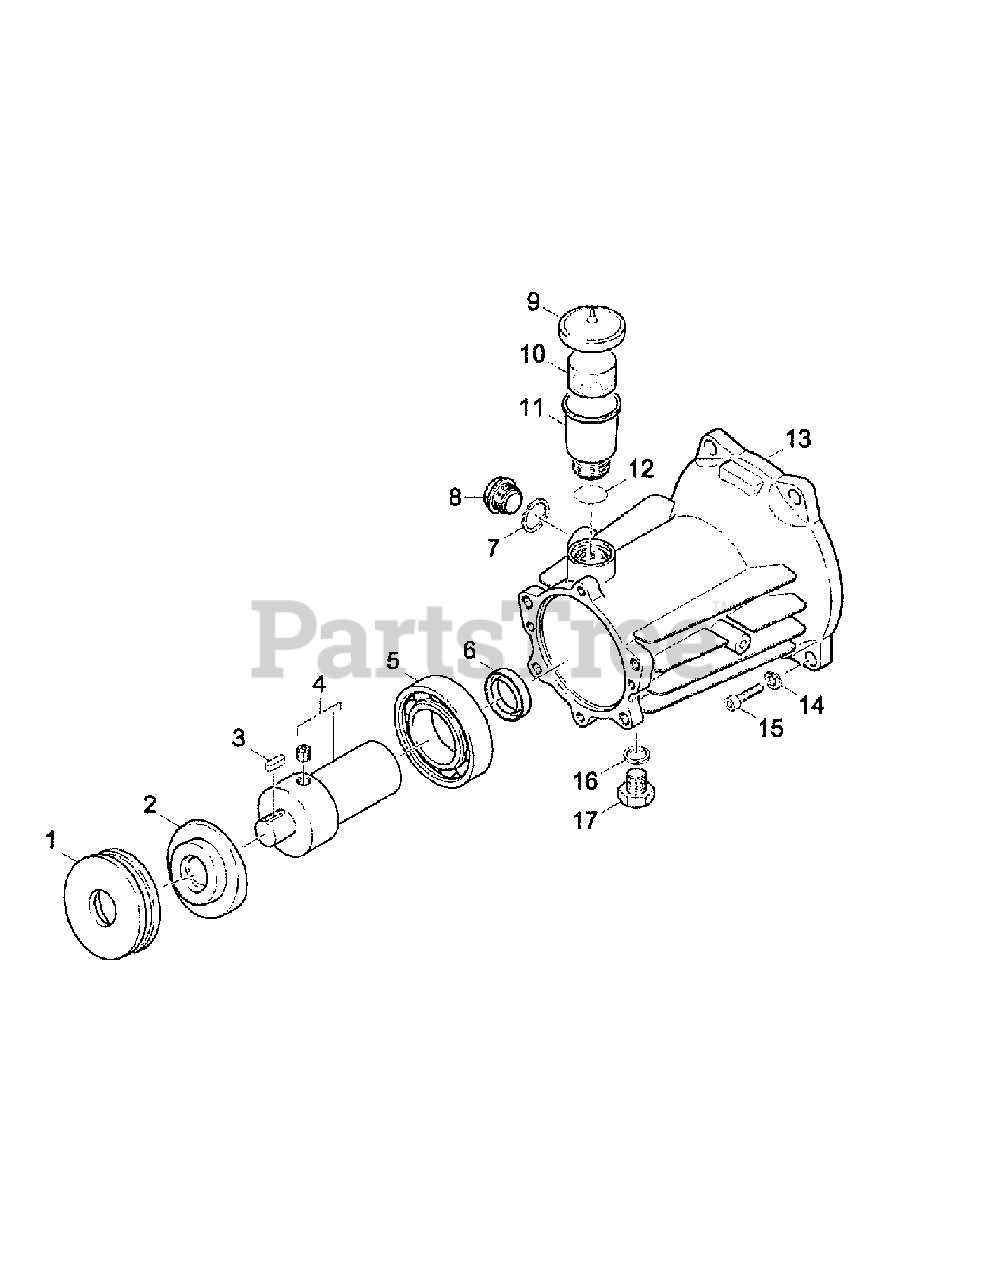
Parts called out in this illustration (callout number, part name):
1	Ball Bearing
2	Swash Plate
3	Spring
4	Coupling
5	Ball Bearing
6	Shaft Seal
7	Seal
8	Closing Screw
9	Cover
10	Plug
11	Tank
12	Gasket
13	Housing
14	Washer
15	Washer
16	Joint Ring
17	Closing Screw
